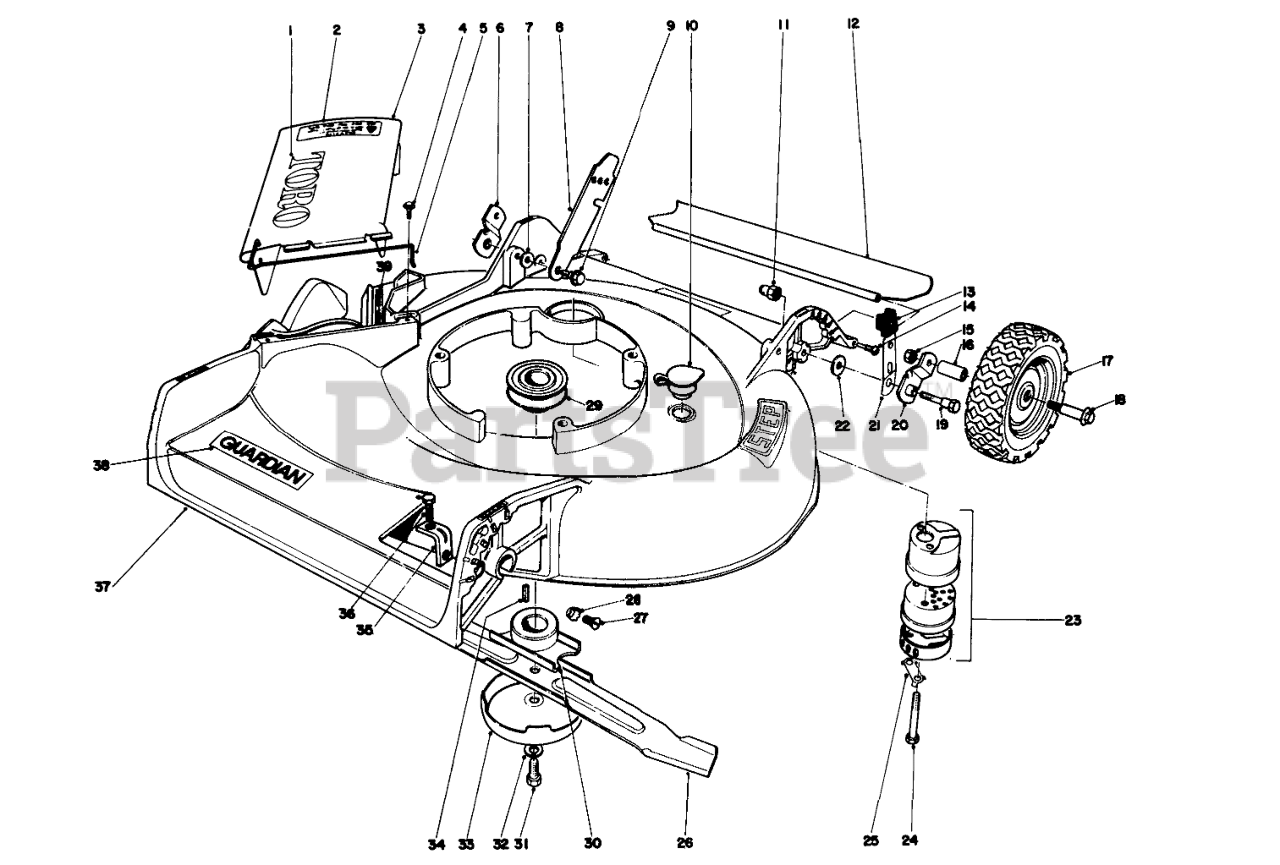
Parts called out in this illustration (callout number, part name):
1	TORO LOGO DECAL
2	Caution Decal
3	Deflector Assembly (Incl. Ref. #1, 2 & 5)
4	SCREW
5	SPRING HINGE
6	Pivot Arm
7	SPACER
8	Latch
9	SCREW-SHOULDER
10	Plug Washout
11	HANDLE PIVOT NUT
12	Rear Shield
13	KNOB-ARM
14	SAFTEY SHIELD SCREW
15	Nut
16	Bushing
17	Wheel & Tire (Incl. Ref. #16)
19	5/16-18 PIVOT SCREW
20	Pivot Arm
21	SPRING ARM ASM
22	WASHER-PIVOT
23	Muffler Assy. (Incl. Ref. #24 & 25)
24	SCREW-HH
25	CLIP - LOCKING
26	Blade
27	5/16-18X5/8 FLT HD MS
28	Lockwasher
29	DRIVER PULLEY
30	Blade Retailer
31	SPECIAL SCREW
32	WASHER-LOCK
33	AntiScalp Cup
34	Key Square
35	Bracket-Gear Box
36	SCREW-HH
37	Housing
38	Decal Deck
39	Decal
